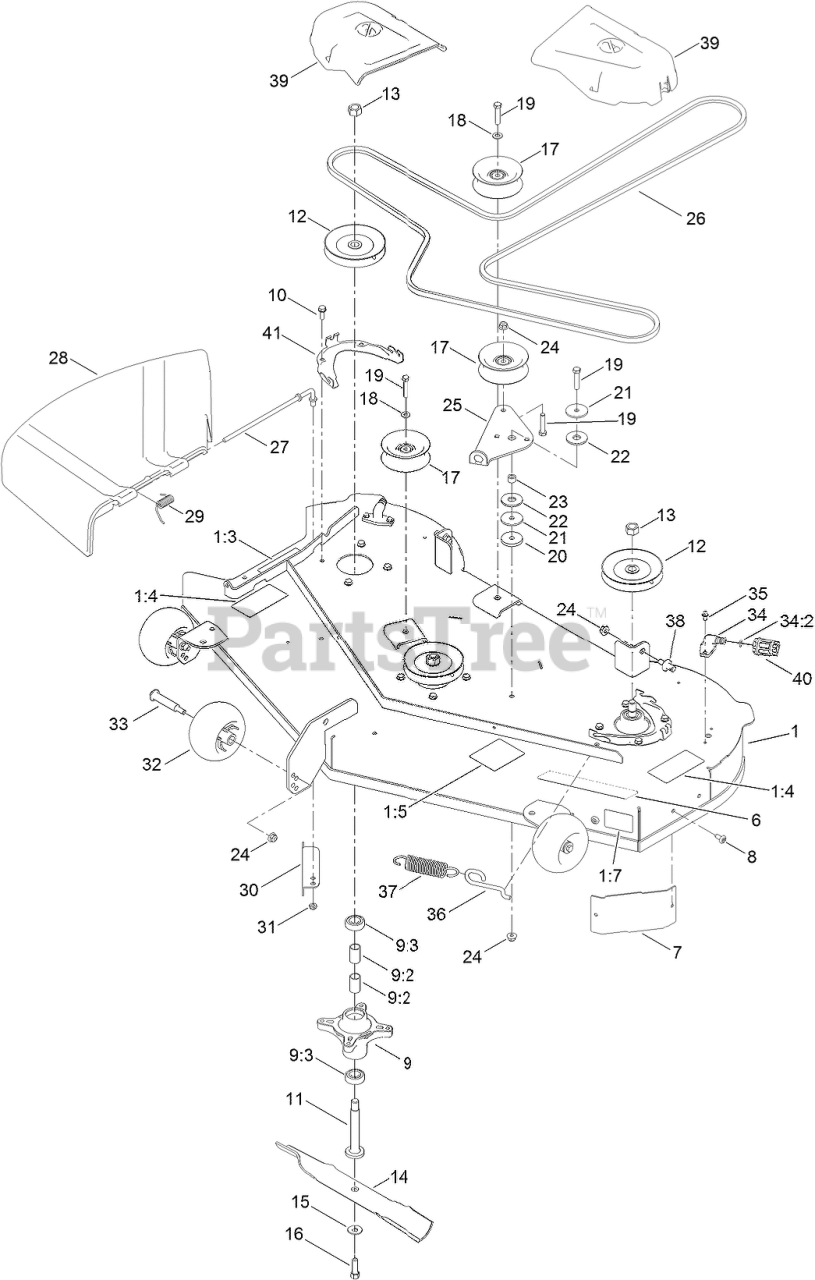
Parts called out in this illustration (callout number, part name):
1	50 INCH DECK AND DECAL ASM
1:3	DECAL-DANGER
1:4	DECAL-DANGER, DECK
1:5	DECAL-ROUTING, BELT
1:7	DECAL-SCALP, ANTI
6	DECAL - DECK
7	BAFFLE-CORNER
9	SPINDLE ASM
9:2	SPACER
9:3	BEARING-BALL
10	SCREW-TAPTITE
11	SHAFT-SPINDLE
12	PULLEY
13	NUT-HEX
14	BLADE-HI LIFT
15	WASHER-BELLEVILLE
16	SCREW-HH
17	PULLEY-IDLER, FLAT
18	WASHER-FLAT
19	SCREW-HH
20	WASHER-PLAIN
21	WASHER-REBOUND
22	WASHER-FRICTION, COMPOSITE
23	SPACER
24	NUT-HF, NI
25	ARM-IDLER
26	V-BELT
27	ROD-PIVOT
28	DEFLECTOR-DISCHARGE
29	SPRING-TORSION
30	BAFFLE-CUTOFF
32	ROLLER-SCALP, ANTI
33	BOLT-SHOULDER
34	FITTING-WASHOUT
34:2	O-RING
35	SCREW-HWH
36	HOOK-RETURN SPRING
37	SPRING-EXTENSION
38	PIN-DECK
39	COVER-BELT
40	CONNECTOR-HOSE
41	BRACKET-COVER, BELT
